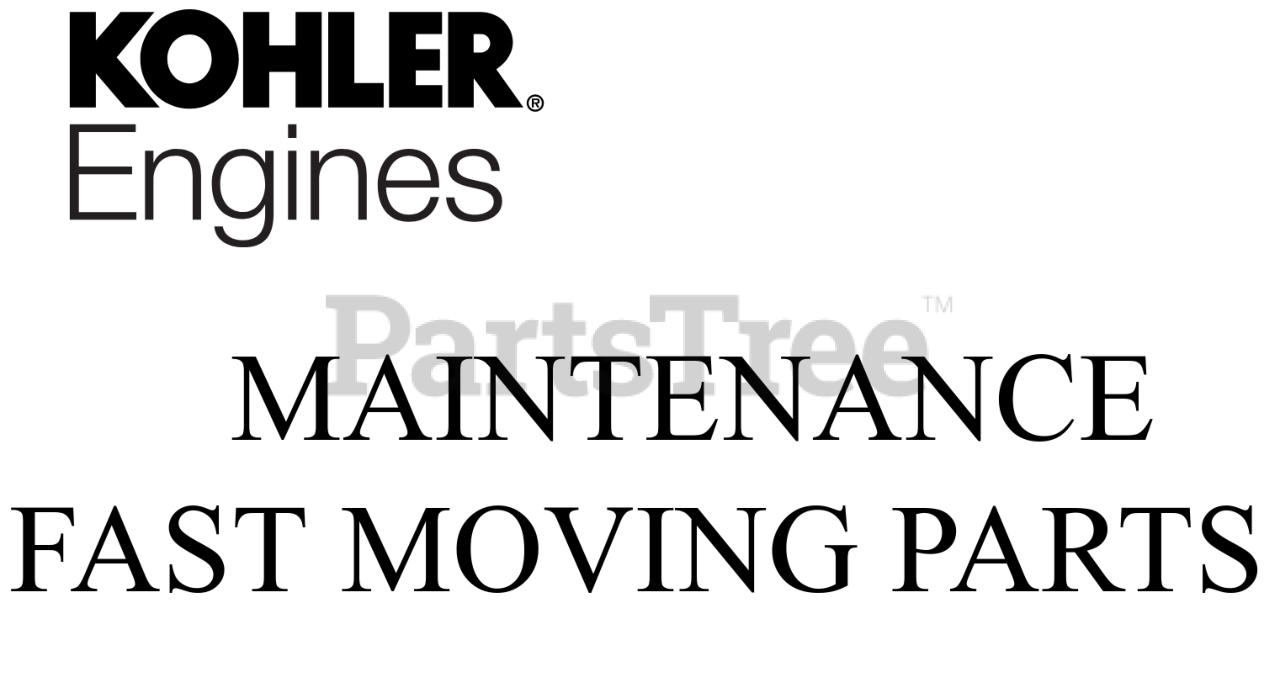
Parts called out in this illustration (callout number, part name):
NI	ELEMENT, AIR FILTER
NI	FILTER,FUEL 75 MICRON (GRAVTY FEED)
NI	SPARK PLUG
